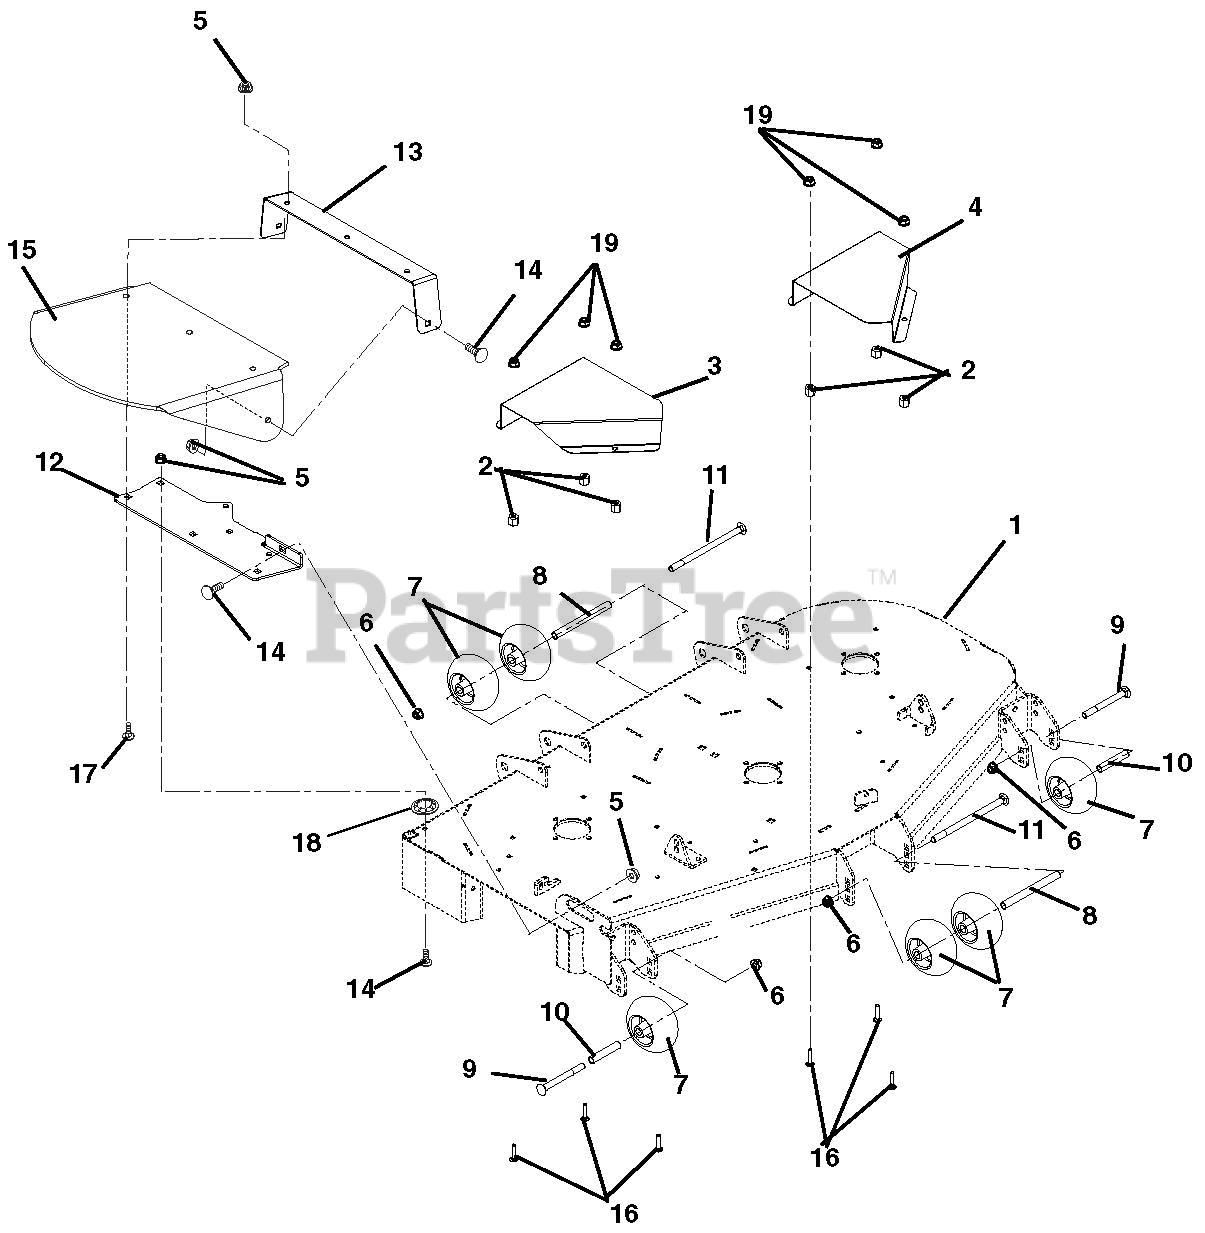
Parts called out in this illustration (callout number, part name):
1	60" 10GA SIDE DISCH DECK -ORNG
1	52" 10GA SIDE DISCH DECK - RED
2	NUT-HEAVY HEX .38-16 YWZC
3	GUARD, 60 RH SPINDLE SHEAVE
3	GUARD, 48-52 SPINDLE SHEAVE
4	GUARD, 60 LH SPINDLE SHEAVE
4	GUARD, 44-52 LH SPINDLE SHEAVE
5	@NUT-LK-NYL-FLG .38-16 YWZC
6	@NUT-LK-NYL-FLG .50-13 YWZC
7	WHEEL, ANTI SCALP
8	SPACER, .510X.625X6.50
9	BLT-RDHDSQNK .50-13X5.00 GR5YZ
10	SPACER, .510X.625X3.35
11	@BLT-RDHDSQNK .50-13X8.50 G5YZ
12	PLATE,DISCH CHUTE SUPPORT (HD)
13	BRKT, DISCHARGE CHUTE (HD)
14	@BLT-RDHDSQNK .38-16X1.00 G5YZ
15	CHUTE, RUBBER DISCHARGE
16	@BLT-HEX .38-16X1.25 GR5 YWZC
17	@BLT-RDHDSQNK .38-16X1.25 G5YZ
18	RETAINER, .38 PUSH-ON
19	@NUT-SPNLK-FLG .375-16 YWZC
